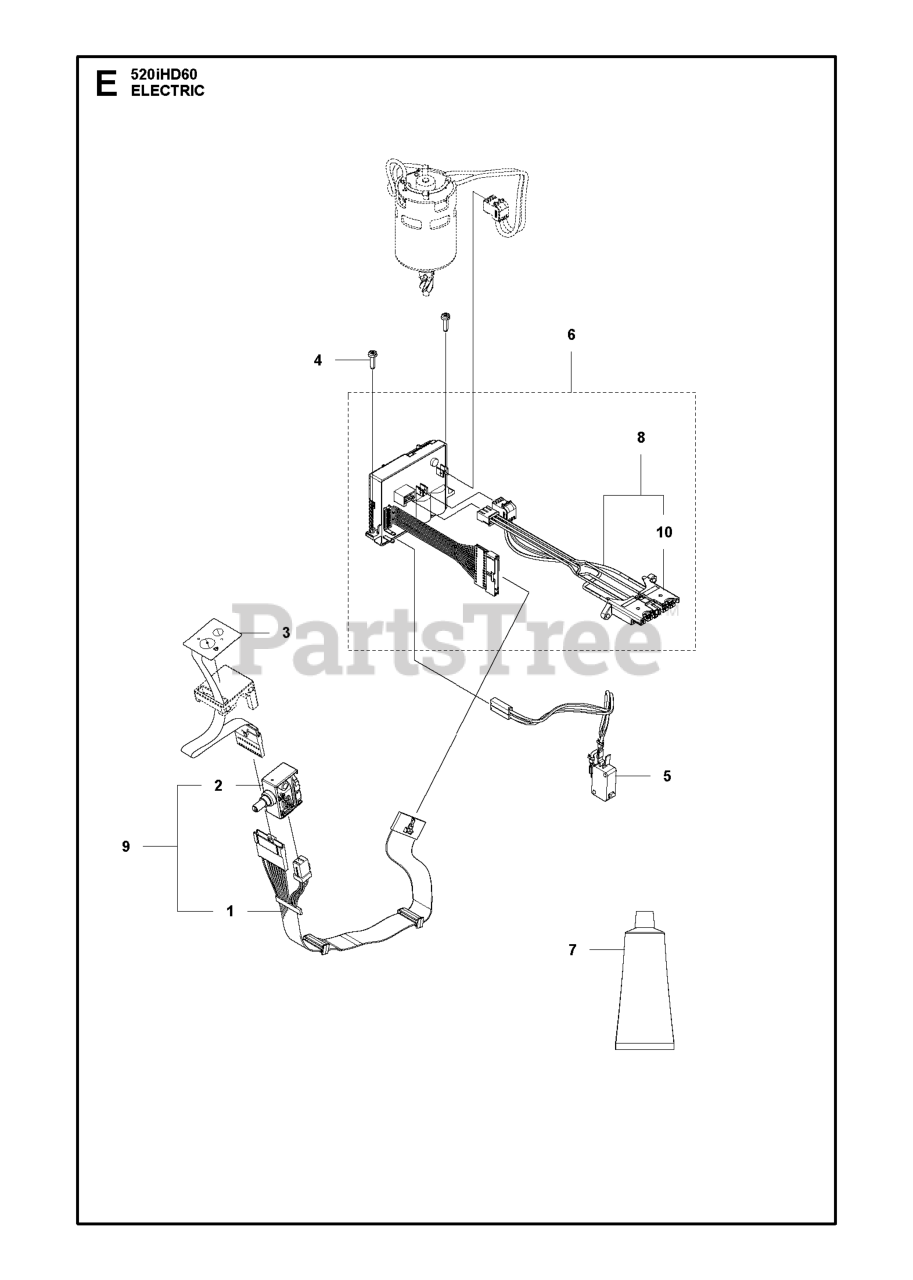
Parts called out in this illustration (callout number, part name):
1	WIRING ASSY TRIGGER HANDLE
2	TRIGGER SWITCH IPX4
3	KEY PAD 2 BUTTON TRIMMER DC (T
5	WIRING ASSY FRONT GUARD
6	CONTROL UNIT PMDC SAFE HEDGE T
7	GREASE TUBE Q8 RUYSDAEL WR2
8	WIRING ASSY
9	SWITCH KIT BATTERY HEDGETRIMME
10	CONNECTOR BATTERY
